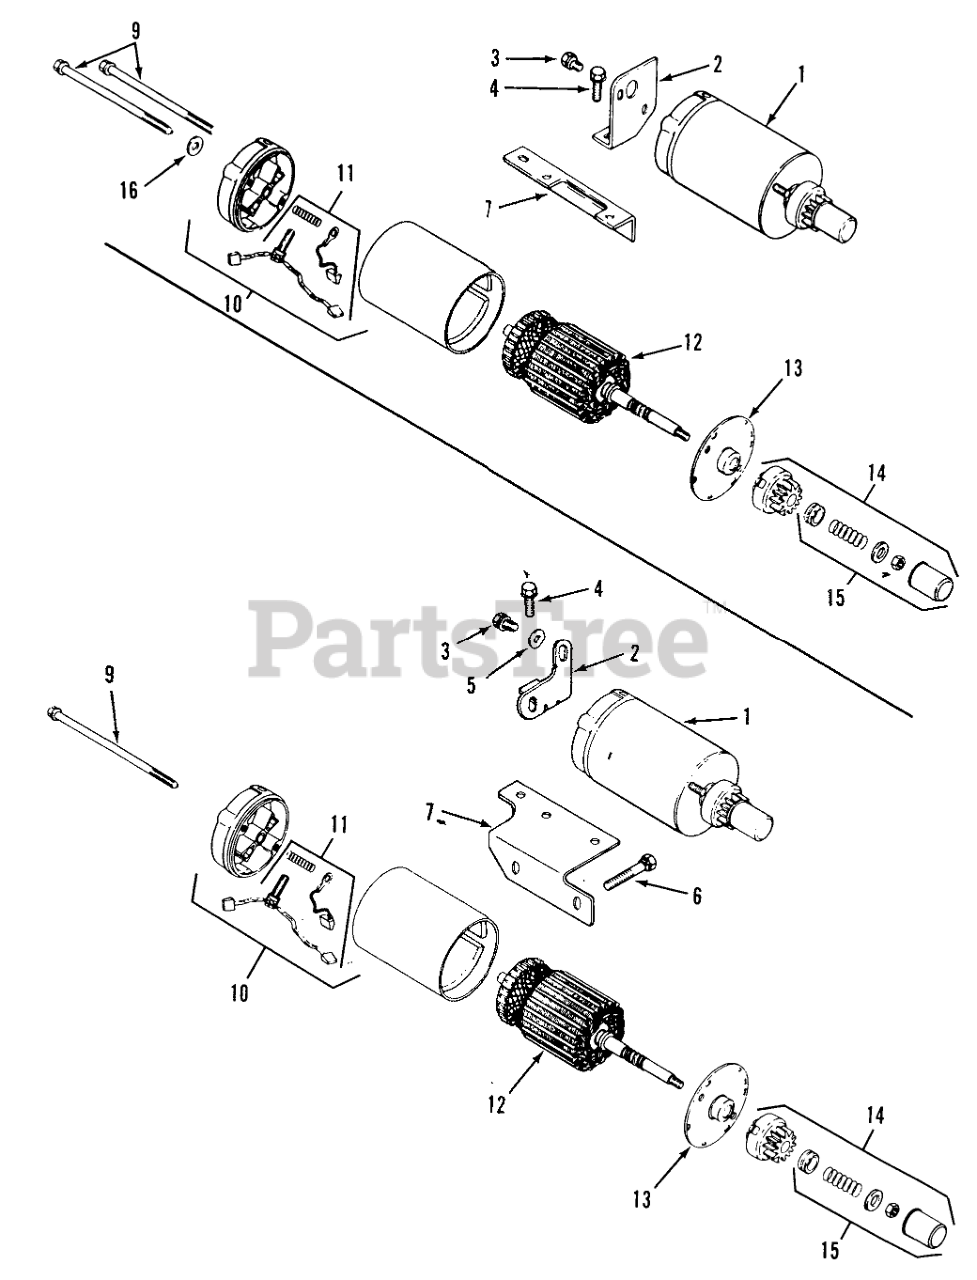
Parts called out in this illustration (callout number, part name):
1	Starter Assembly (Includes Items 9 thru 15)
2	Brace-Tail
3	Screw
4	Screw
6	Screw
7	Bracket-Solenoid
9	Bolt
10	Commutator End Cap Assembly (Includes Item 11)
11	Kit-Brush
12	Armature
13	Cap-Drive End
14	Drive Kit (Includes Item 15)
15	Kit-Drive Parts
